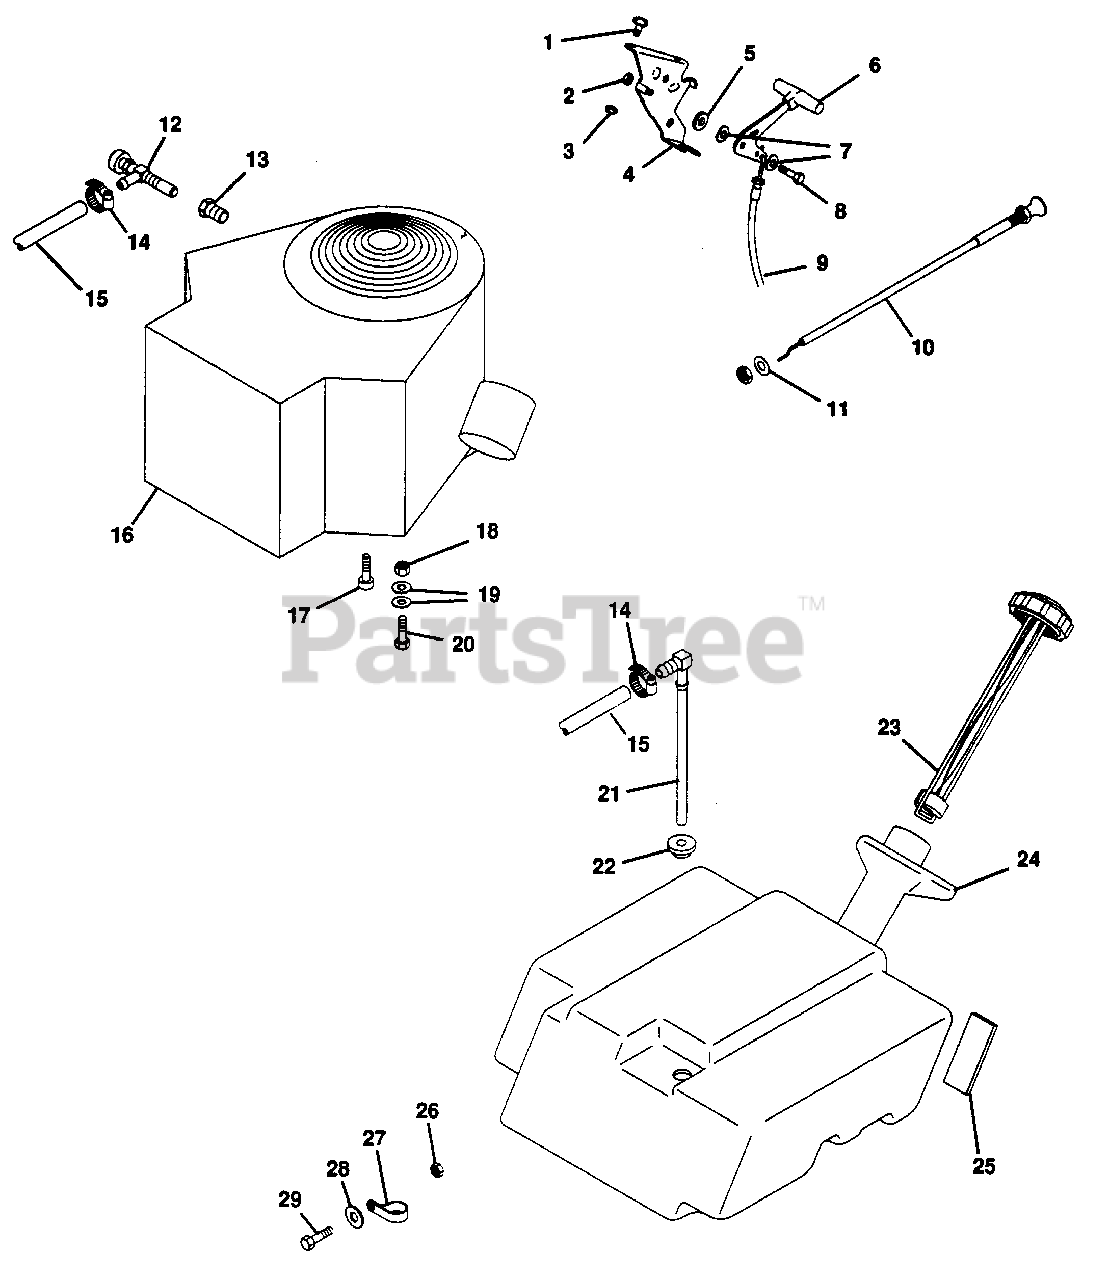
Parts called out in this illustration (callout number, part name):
1	Screw, Mach. 10-24 x .625 PHD
2	Nut, Lock 1/4-28
3	Nut, Lock 10-24
4	Bracket, Mounting L.H.
5	Washer, Flat .281 x .625 x .065
6	Assembly, Knob and Lever
7	Washer, Spring
8	Bolt, Hex 1/4-28 x .625
9	Assembly, Conduit
10	Control, Choke
11	Washer, Flat .406 x .812 x .065
12	Cock, Oil Drain
13	Adaptor, Oil Drain
14	Clamp, Hose
15	Line, Fuel .5 OD x .25 ID
16	Engine, 16 HP B & S
17	Screw, M8 x 1.25 x 20mm SOC HD
18	Nut, Lock 5/16-18
19	Washer, Flat .344 x .688 x .065
20	Bolt, Hex 5/16-18 x 1.75
21	Fitting, Tank
22	Bush., .563 x 1.06 x .688
23	Fuel Gage and Cap
24	Tank, Fuel
25	Pad, Gas Tank
26	Nut, Lock 5/16-18
27	Clamp, Steel .625
28	Washer, Flat .313 x .875 x .065
29	Bolt, Hex 5/16-18 x 1.00
